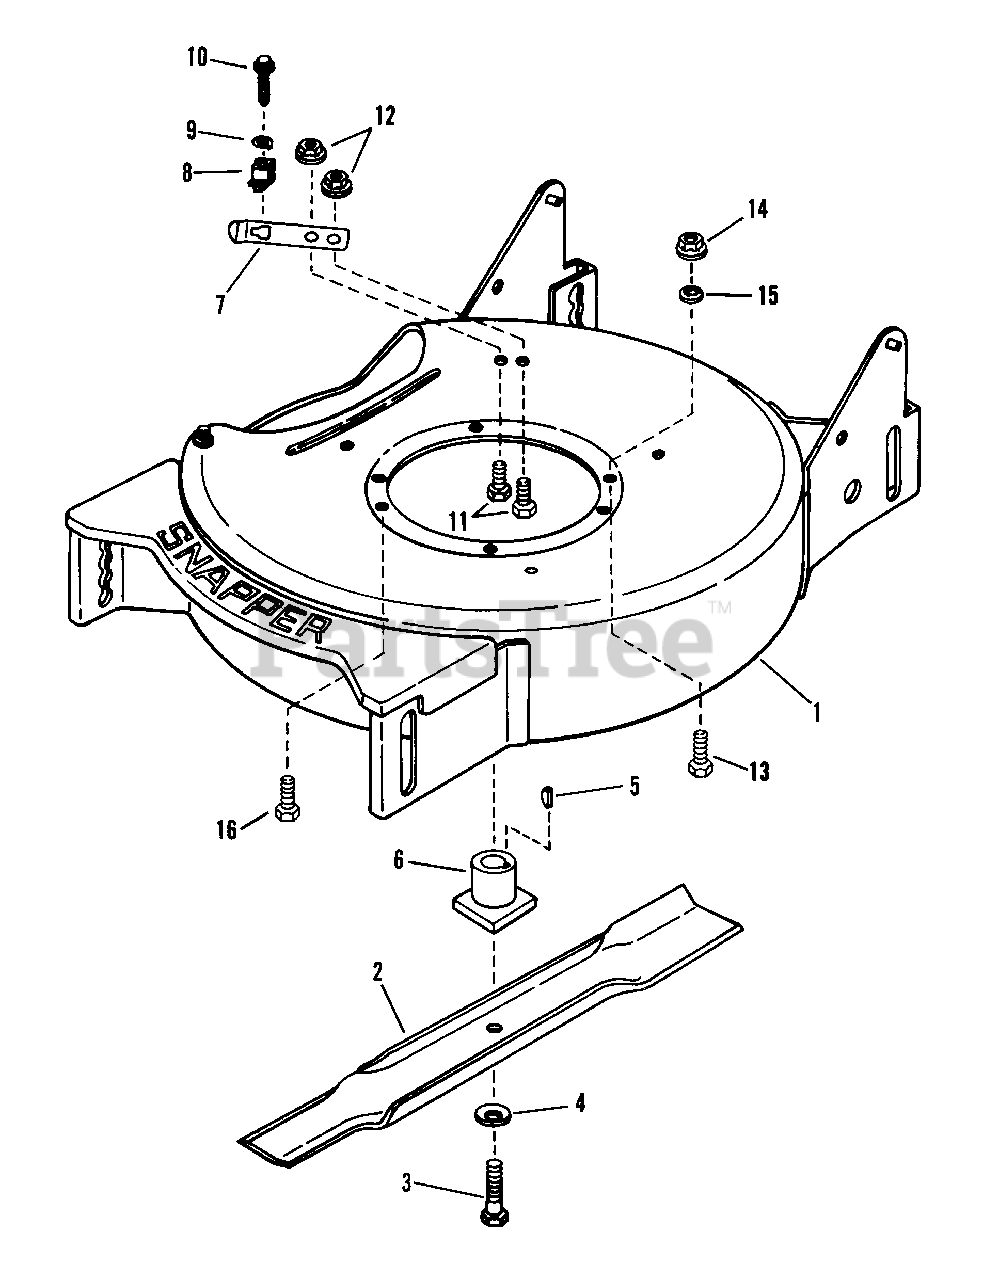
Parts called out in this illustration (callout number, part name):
1	*DECK, Structure (Short engine mount)
2	BLADE, Cutter
3	SCREW, 3/8-24 x 2" Hex Head Cap, Grade 5
4	WASHER, Cone
5	KEY, Hi-Pro
6	HUB, Blade Drive
7	SPRING, Interlock
8	INSULATOR, Interlock
9	WASHER, #8 Tab
10	SCREW, #8-18 x 3/4" Self-Tapping
11	SCREW, 1/4-20 x 1/2" Hex Head Cap, Grade 5
12	NUT, 1/4-20 Hex Flange Lock
13	SCREW, 5/16-18 x 5/8" Hex Head Cap
14	NUT, 5/16-18 Hex Flange Lock
15	RETAINER, 5/16 Bolt
16	SCREW, 3/8-16 x 1" Hex Washer Self-Tap
